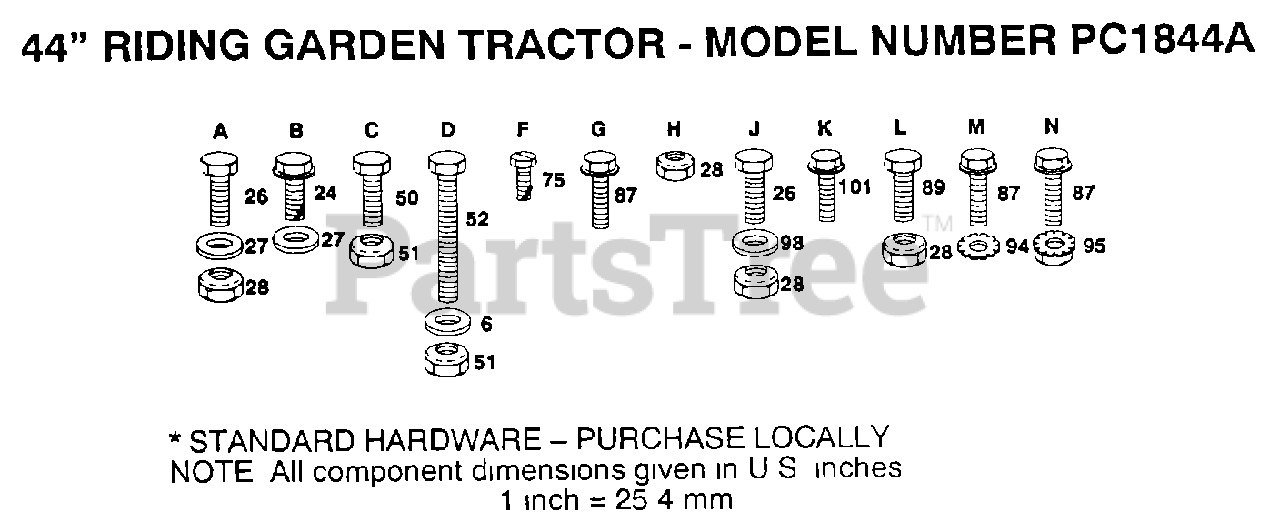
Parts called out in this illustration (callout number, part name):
6	WASHER
24	SCREW
26	BOLT
27	WASHER
50	BOLT
52	BOLT HEX
75	SCREW LT
87	SCREW LT
94	LOCKWASHER
95	NUT
98	WASHER
101	SCREW
